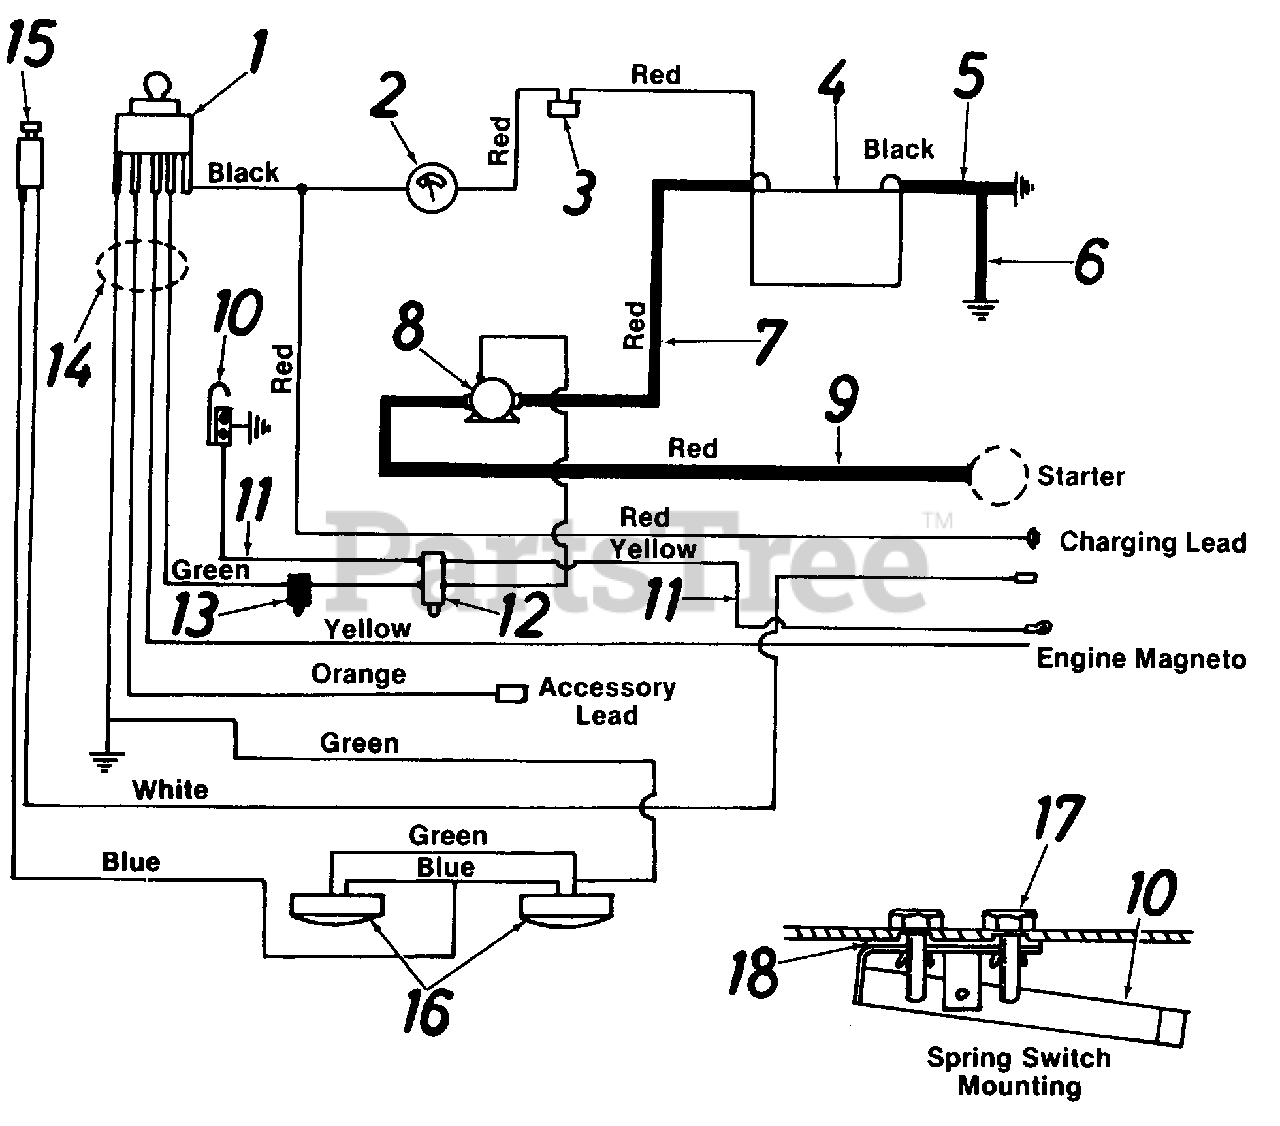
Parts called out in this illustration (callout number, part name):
1	Ignition Switch
2	Ammeter
3	Circuit Breaker
4	Battery
5	Electric Wire
6	Electric Wire
7	Electric Wire
8	Solenoid
9	Electric Wire
10	Spring Switch
11	Reverse Lockout Wire Ass'y.
12	Safety Switch
13	Safety Switch-Black
14	Basic Harness
15	Light Switch
16	Headlights
17	Hex Wash. Hd. Tap Scr. #8 x 1/2 Lg.
18	Insulator Nut Plate
